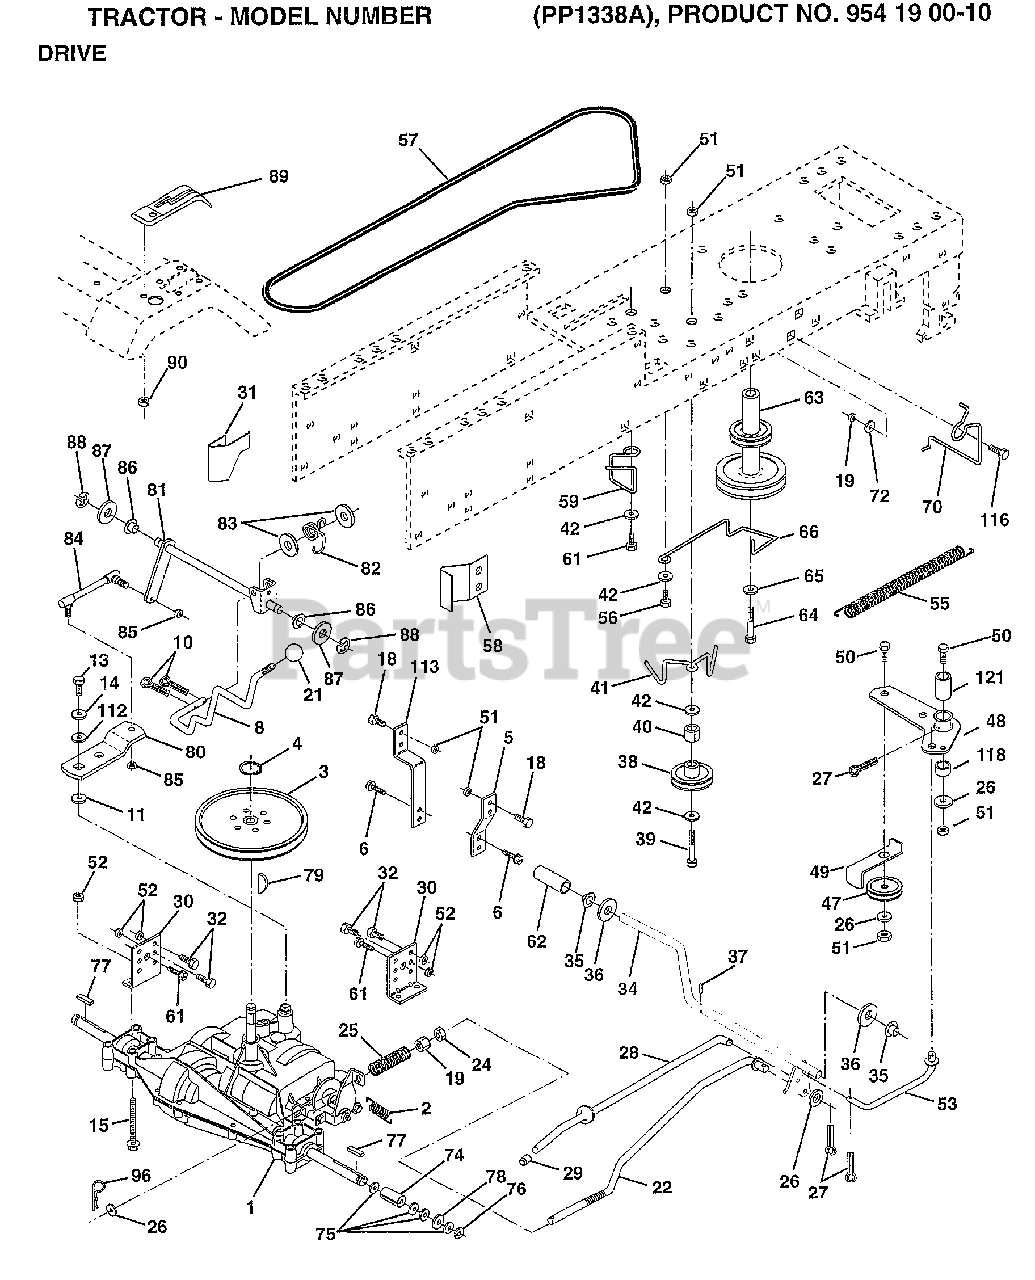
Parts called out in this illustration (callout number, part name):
2	SPRING.BRAKE.RETU
3	PULLEY TRANS
5	STRAP TORQUE
6	SCREW
8	ROD SHIFT FEND LT
10	PIN COTTER 1/8
11	WASH-SHFT PLT LT
13	BOLT.1/4-28.W/PAT
14	LOCKWASHER
15	BOLT.HX.FLG.5/16
18	BOLT
19	NUT
21	KNOB T (1/2-HOLE)
22	BRAKE ROD
24	NUT
25	SPRING ROD LT
26	WASHER
27	COTTER PIN
28	ROD.BRAKE.PARK.LT
29	PLUNGER CAP T
30	TRANSAXLE MTG BKT
31	"KEEPER,BELT LH T"
32	BOLT
34	SHAFT ASM-PEDAL F
35	NYLON BEARING
36	WASHER LT
38	IDLER, FLAT
39	BOLT
40	SPACER T
42	WASHER
48	BELLCRANK ASM
49	RETAIN BELT
53	"LINK, CLUTCH T"
55	"SPRING, RETURN LT"
58	"KEEPER,BELT RH T"
59	KEEPER BELT CNTSP
61	SCREW
62	PEDAL COVER T
63	PULLEY.ENGINE
64	BOLT
65	LOCKWASHER
66	KEEPER-BELT
70	KEEPER BELT ENG
72	WASHER
74	SPACER AXLE
75	WASHER
76	E-RING LT
77	SQUARE KEY
78	WASHER
80	"ROD,LINK SHIFT"
81	SHAFT ASM SHIFT
82	"SPRING,TORSION"
83	WASHER
84	"ROD,TIE "
85	NUT.CNT.LOCK.1/4
86	BUSHING
87	WASHER D
88	KLIP RING
90	NUT
96	RETAINER M
112	WASHER LT
113	"STRAP,TORQUE"
116	BOLT RDHD 3/8-16
118	SPACER-BELLCRANK
121	NYLINER-CLUTCHING
